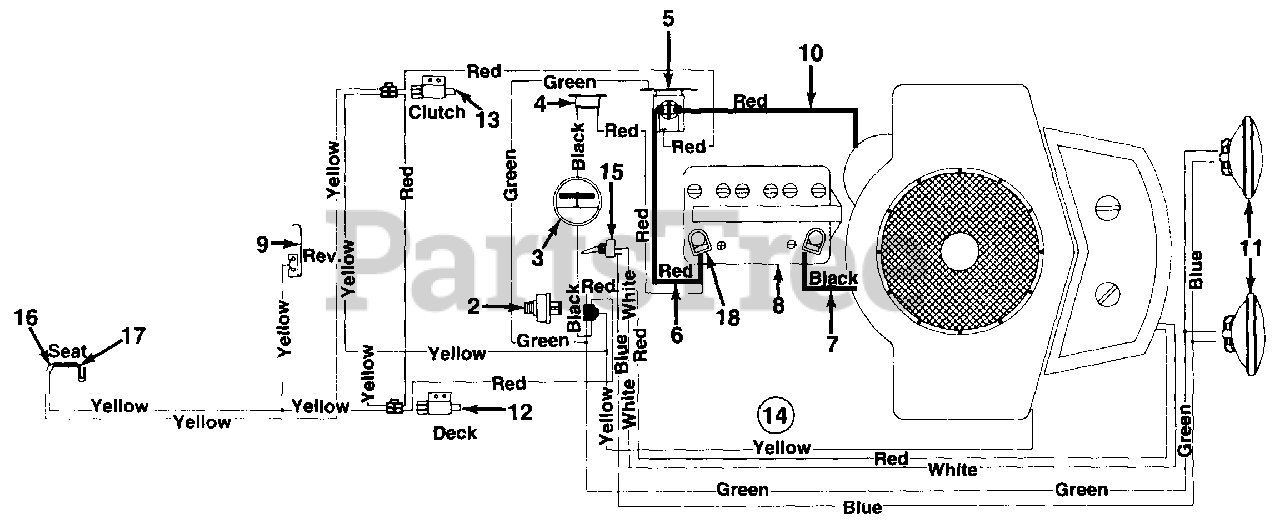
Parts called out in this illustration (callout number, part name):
2	Ignition Switch
3	Ammeter
4	Circuit Breaker
5	Solenoid
6	Electric Wire
7	Electric Wire
8	Battery
9	Spring Switch (Reverse Safety)
10	Electric Wire
11	Headlights
12	Safety Switch (PTO)
13	Safety Switch (Clutch)
14	Wire Harness
15	Light Switch
16	Safety Switch (Seat)
17	Safety Switch (Seat)
18	Battery Boot
